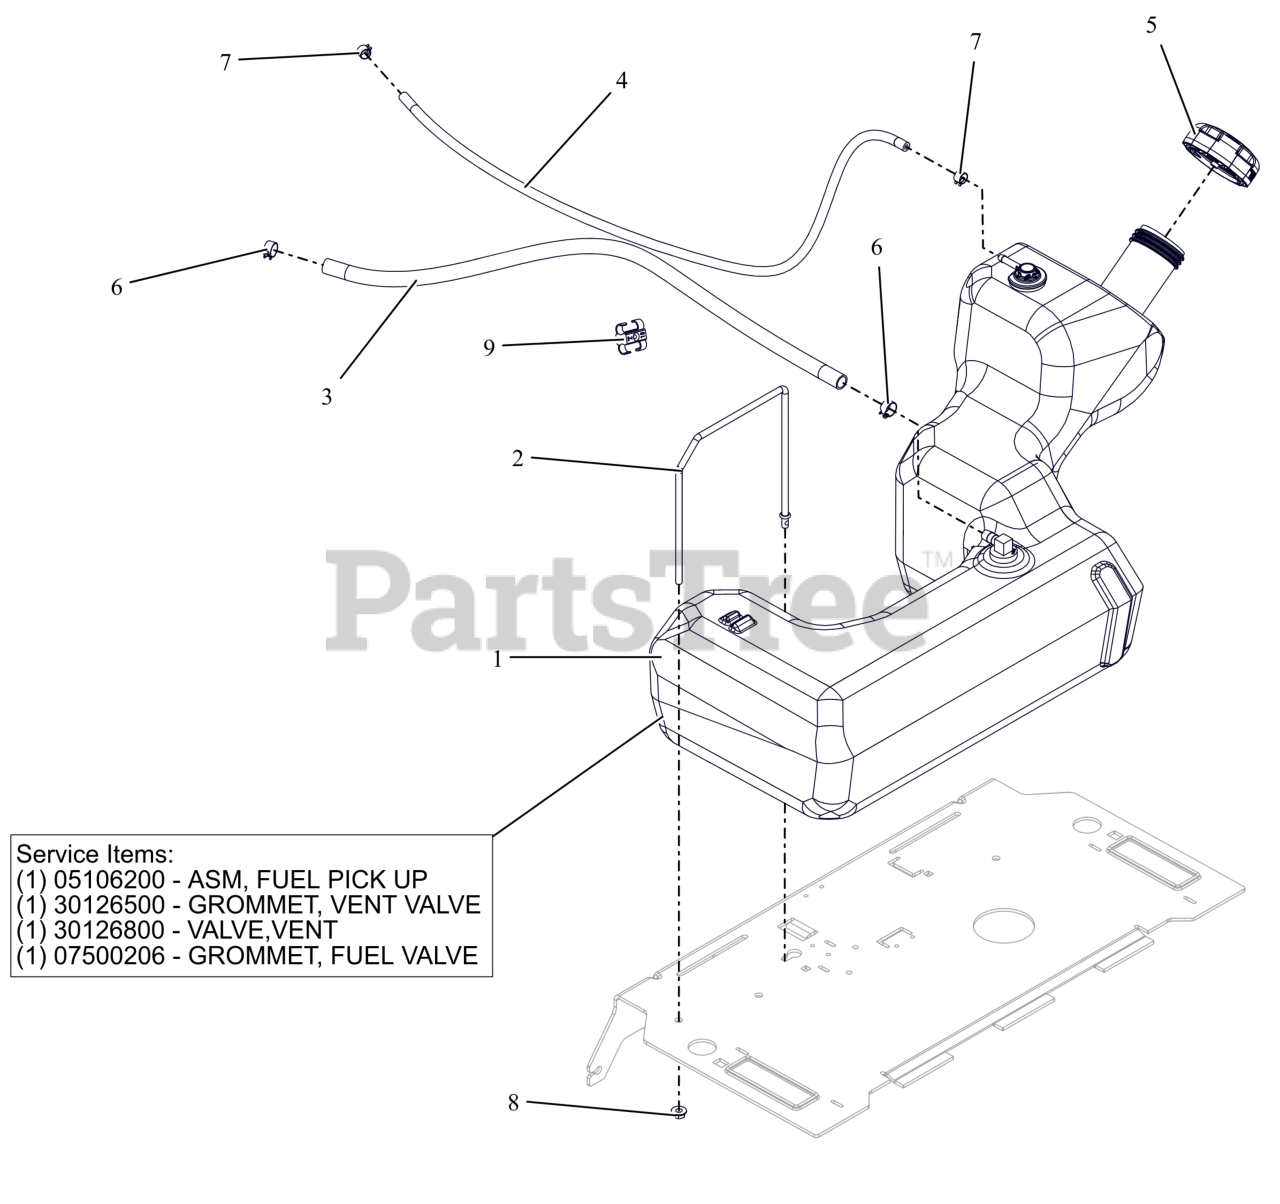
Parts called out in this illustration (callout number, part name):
1	ASM, FUEL TANK - IKON 23
1	ASM, IKON FUEL PICK-UP
1	GROMMET, VENT VALVE
1	VALVE, VENT
1	BSHG-FLG .375X1.062X.625 NITR
2	STRAP, TANK HOLD DOWN
3	1 INCH OF HOSE, .25 LOW-PERM BULK GAS
4	HOSE, .188 30R7 BULK
5	CAP-FUEL- 2.25 RATCHET INLET V
6	CLAMP, FUEL LINE
7	CLAMP-HOSE, SPRING .188
8	NUT-LK-CTR-FLG .25-20 ZC120
9	CLIP, T, .38-.50
